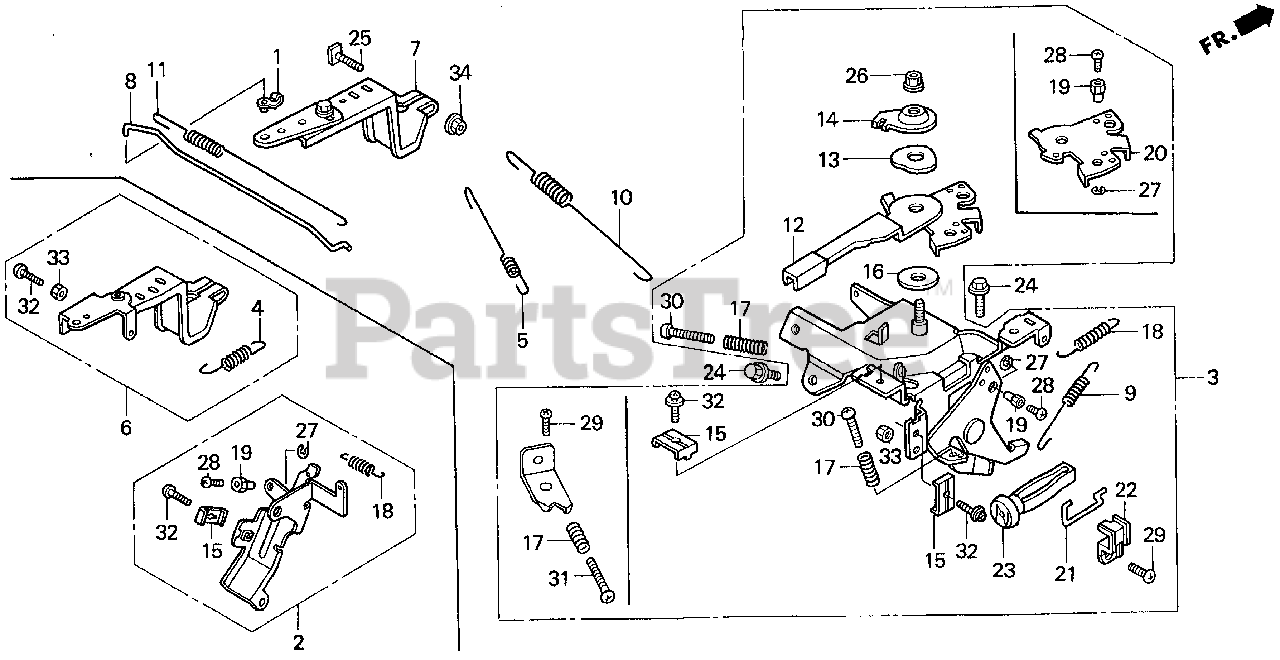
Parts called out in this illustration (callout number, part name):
1	JOINT, ROD
3	CONTROL ASSY. (REMOTE)
5	SPRING, STARTER
7	ARM, GOVERNOR
8	ROD, GOVERNOR
10	SPRING, GOVERNOR
11	SPRING, THROTTLE RETURN
13	SPRING, LEVER
14	WASHER, CONTROL LEVER
15	HOLDER, CABLE
16	SPACER, CONTROL LEVER
17	SPRING, CONTROL ADJUSTING
18	SPRING, CABLE RETURN
19	HOLDER, WIRE
20	LEVER, WIRE
24	BOLT, FLANGE (6X12) (CT200)
25	BOLT, GOVERNOR ARM
26	NUT, SELF-LOCK (6MM)
27	CIRCLIP (5MM)
28	SCREW, PAN (4X6)
30	SCREW, PAN (5X25)
32	SCREW, PAN (5X16)
32	SCREW-WASHER (5X16)
34	NUT, FLANGE (6MM)
